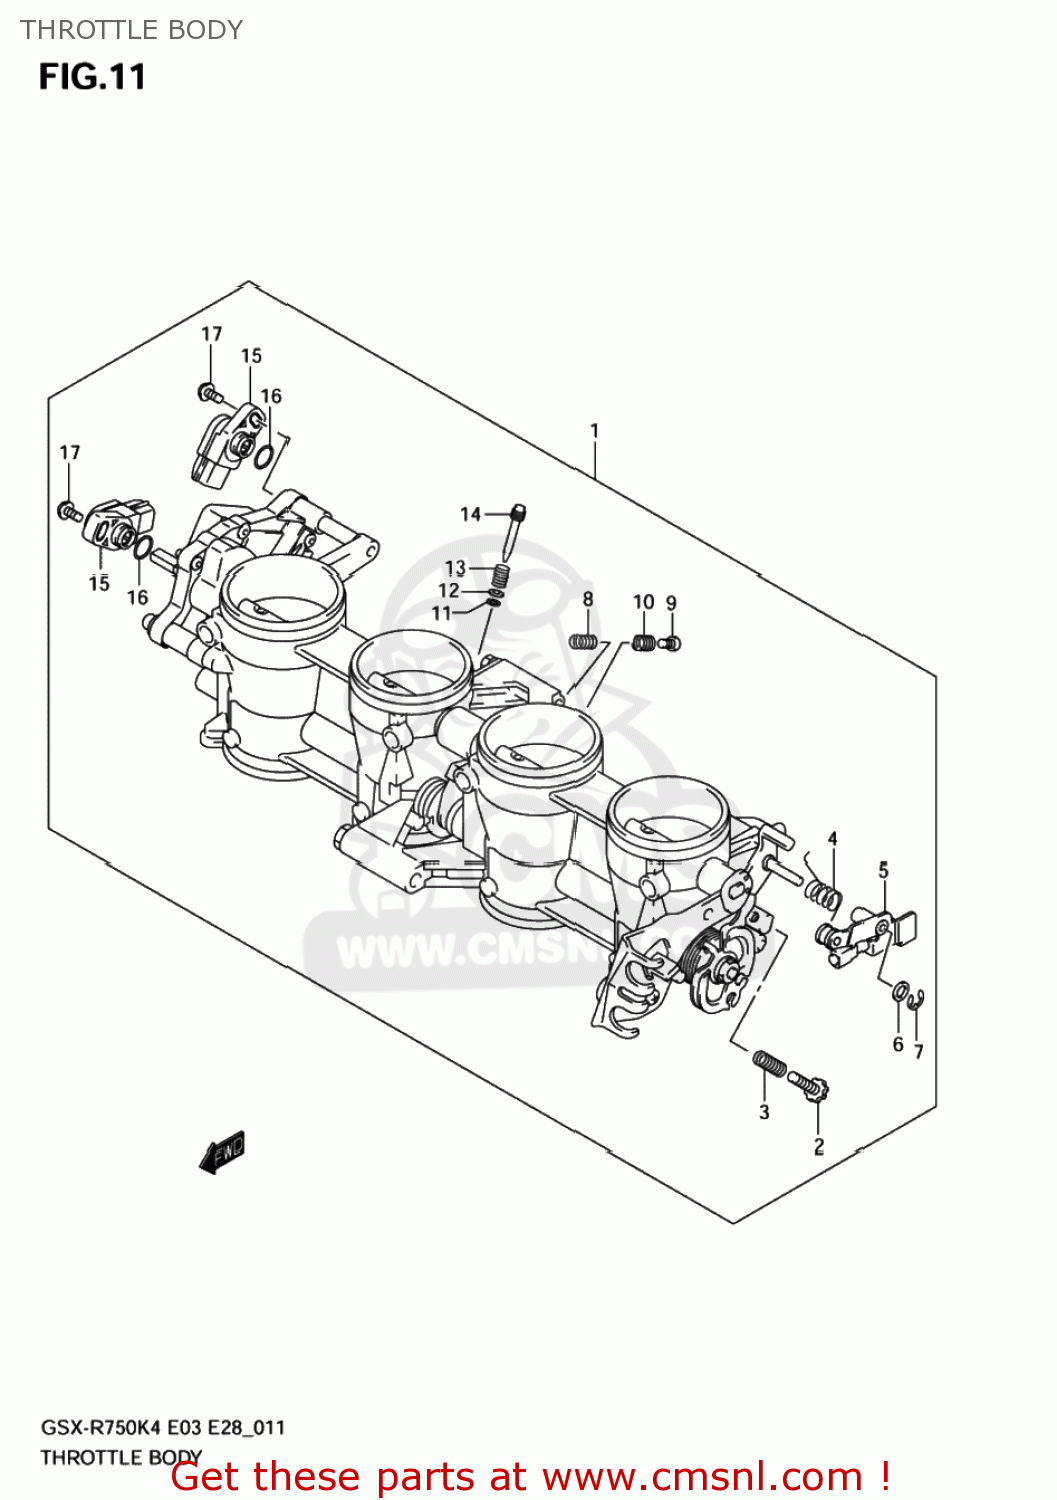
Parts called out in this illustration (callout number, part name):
1	BODY ASSY,THROTTLE
2	SCREW
3	SPRING
4	SPRING,TORSION
5	LEVER ASSY
6	PACKING (NAS)
7	E RING
8	SPRING
9	SCREW
10	SPRING
11	O RING,PILOT AIR SCREW
12	WASHER
13	SPRING,THROTTLE SCREW
14	SCREW
15	SENSOR ASSY
16	O RING
17	SCREW
